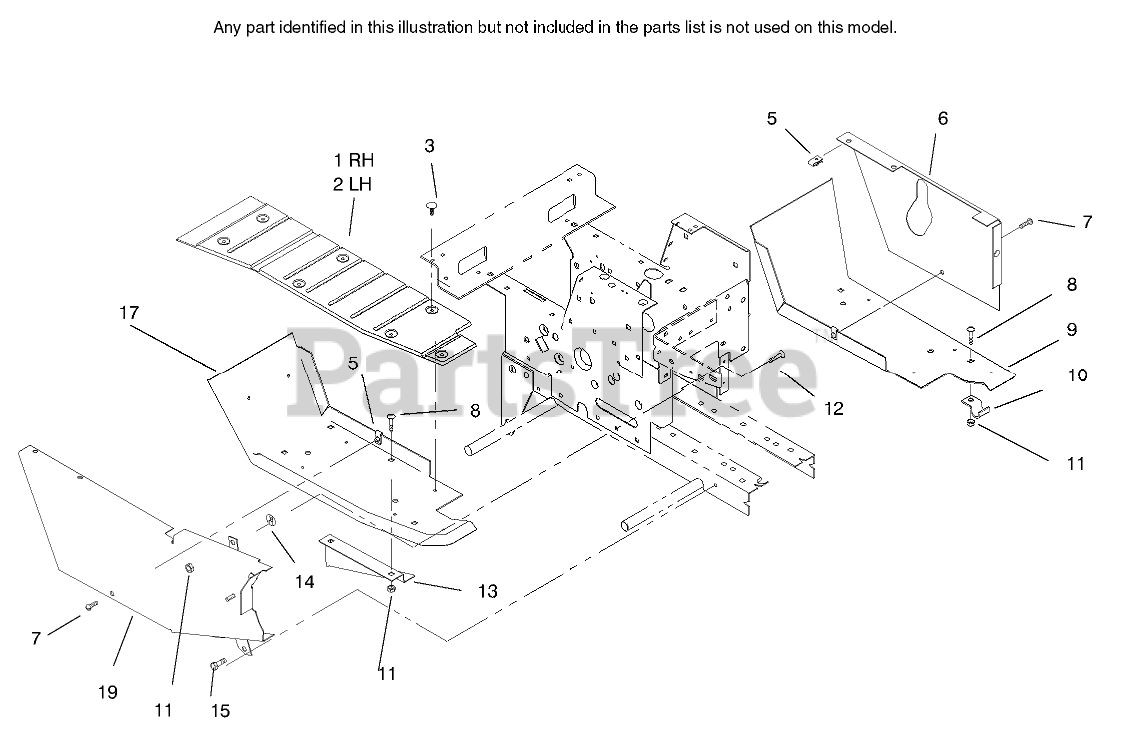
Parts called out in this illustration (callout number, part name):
1	PAD-FOOT RH
2	PAD-FOOT LH
3	FASTENER-PANEL
6	COVER-LH
7	SCREW-PPH
8	BOLT-CARR
9	PINION SHAFT
9	FOOTREST-LH
10	BRACKET
11	NUT-LOCK, NI
12	BOLT-CARR
13	GUIDE-LOWER BELT
14	NUT-PUSH
15	Bolt
17	FOOTREST-RH
18	Decal-Certification
19	SINGLE BELT GUARD ASM
